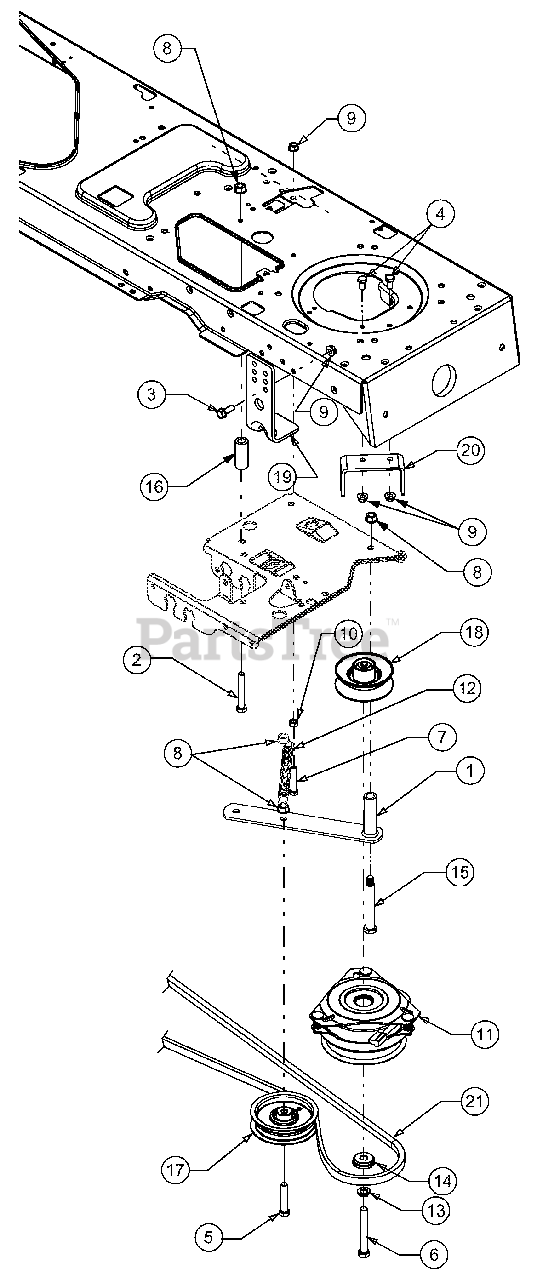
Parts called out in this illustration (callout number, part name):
3	Screw, 5/16-18, .875
4	Screw, 5/16-18 x .625 GR5
5	Screw, 3/8-16, 2.0 GR5
6	Screw, 7/16-20 x 3.25 GR5
7	Screw, 5/16-18 x 1.75 GR5
8	Nut, Flange Lock, 3/8-16
9	Nut, Flange Lock, 5/16-18
10	Nut, 5/16-18 GR5
11	Clutch, Electric PTO
12	Spring, Extension .62 x 5.622
13	Washer, Lock, 7/16, Regular Duty
14	Spacer, Shoulder, 1.38 x .445 x .36
15	Screw, Shoulder, .498 x 3.245: 3/8-16
16	Spacer, 3/8 x .635 x 1.54
17	Pulley, Idler, 3.5
18	Pulley, Engine
